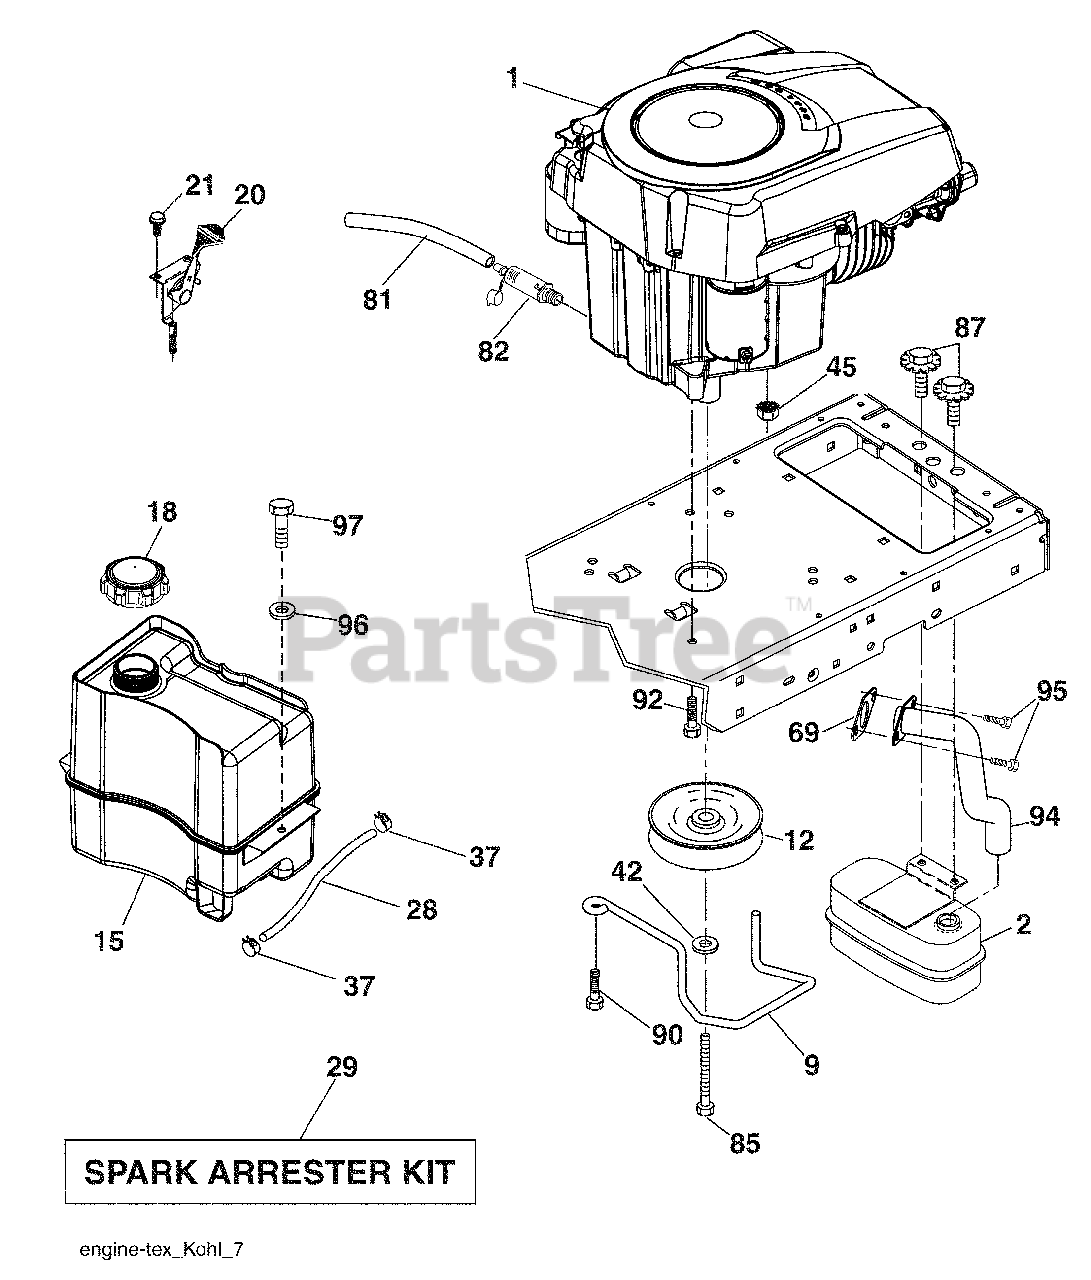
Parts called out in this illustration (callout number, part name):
9	Keeper Belt Engine
12	Pulley Engine
15	Tank Fuel
18	Cap Asm
20	Control Throttle
21	Screw # 10 x 0.750
28	Fuel Line
29	Spark Arrester Kit
37	Clamp Hose
42	Washer Lock 7/16
45	Nut Keps Hex 1/4-20 unc
81	Tube Drain Oil Easy
82	Plug Drain Oil
85	Bolt Hex 7/16-20 x 4 x Gr. 5-1.5 Thr
87	Bolt 5/16-18 unc x 3/4 w/Sems
90	Screw 3/8-16 x 1
92	Screw 3/8-16 x 1
94	Tube Exhaust
95	Screw Socket Hd. 5/16-18 x .75
96	Washer 9/32 x 7/8 x 16 Ga.
97	Screw 1/4-20 x 3/4
